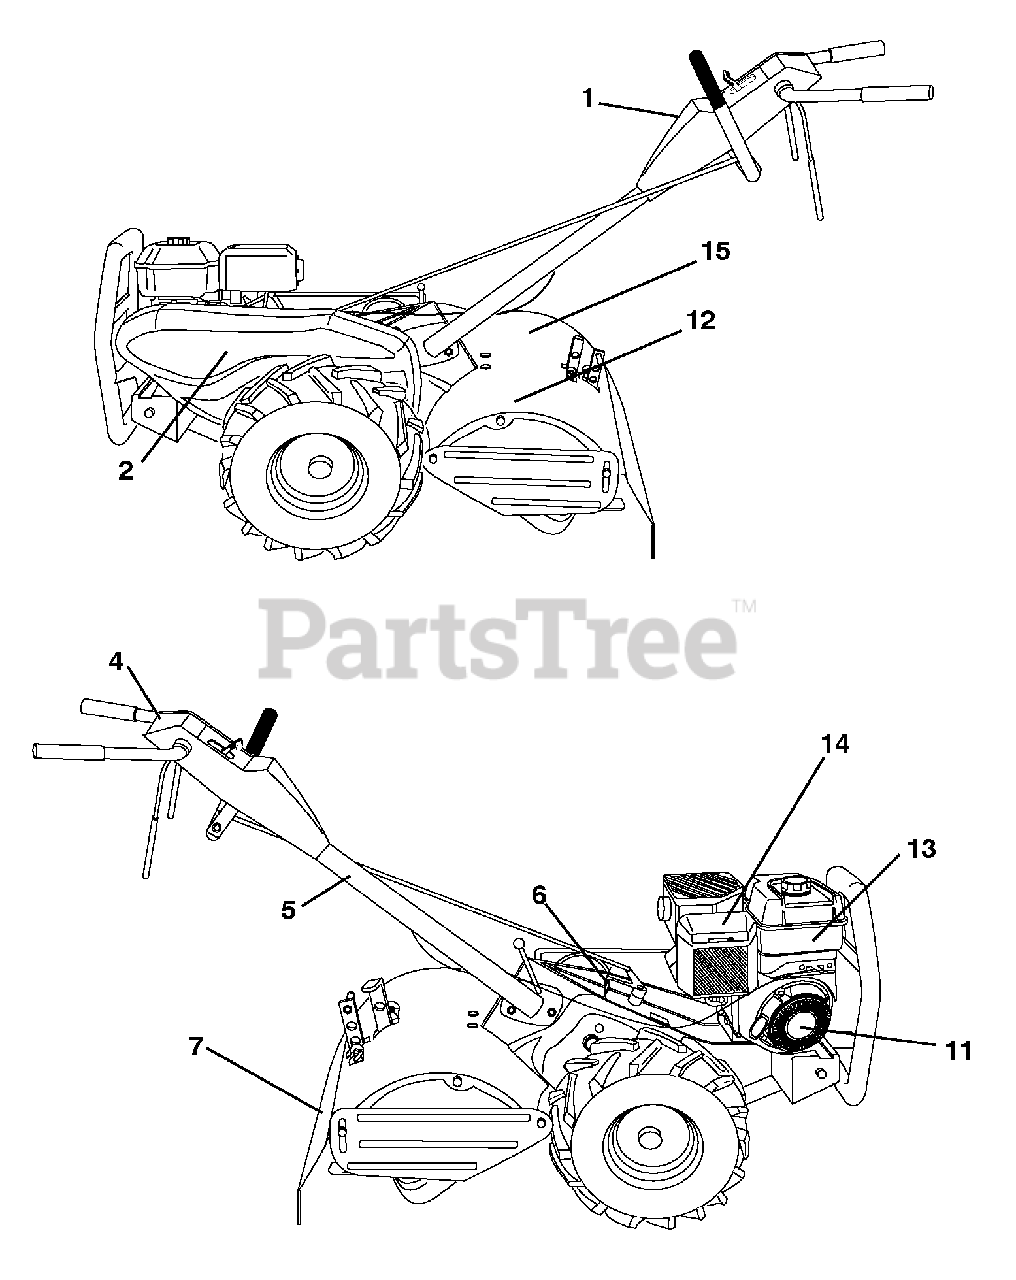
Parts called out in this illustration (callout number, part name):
1	Decal, CNTRL PNL
2	Decal, Decal, Blt Grd
4	Decal, Instruction, Tilling
5	Decal, Hand Placement
6	Decal, Shift Indicator
7	Decal, caution
11	Decal, Rewind
12	Decal Tine Direction Front
13	Decal, B&S Tank
14	Decal, B&S Air Cleaner
15	Decal ?Tine Direction Rear
15	Manual, Operator's (E&F)
15	Manual, Parts (E&F)
